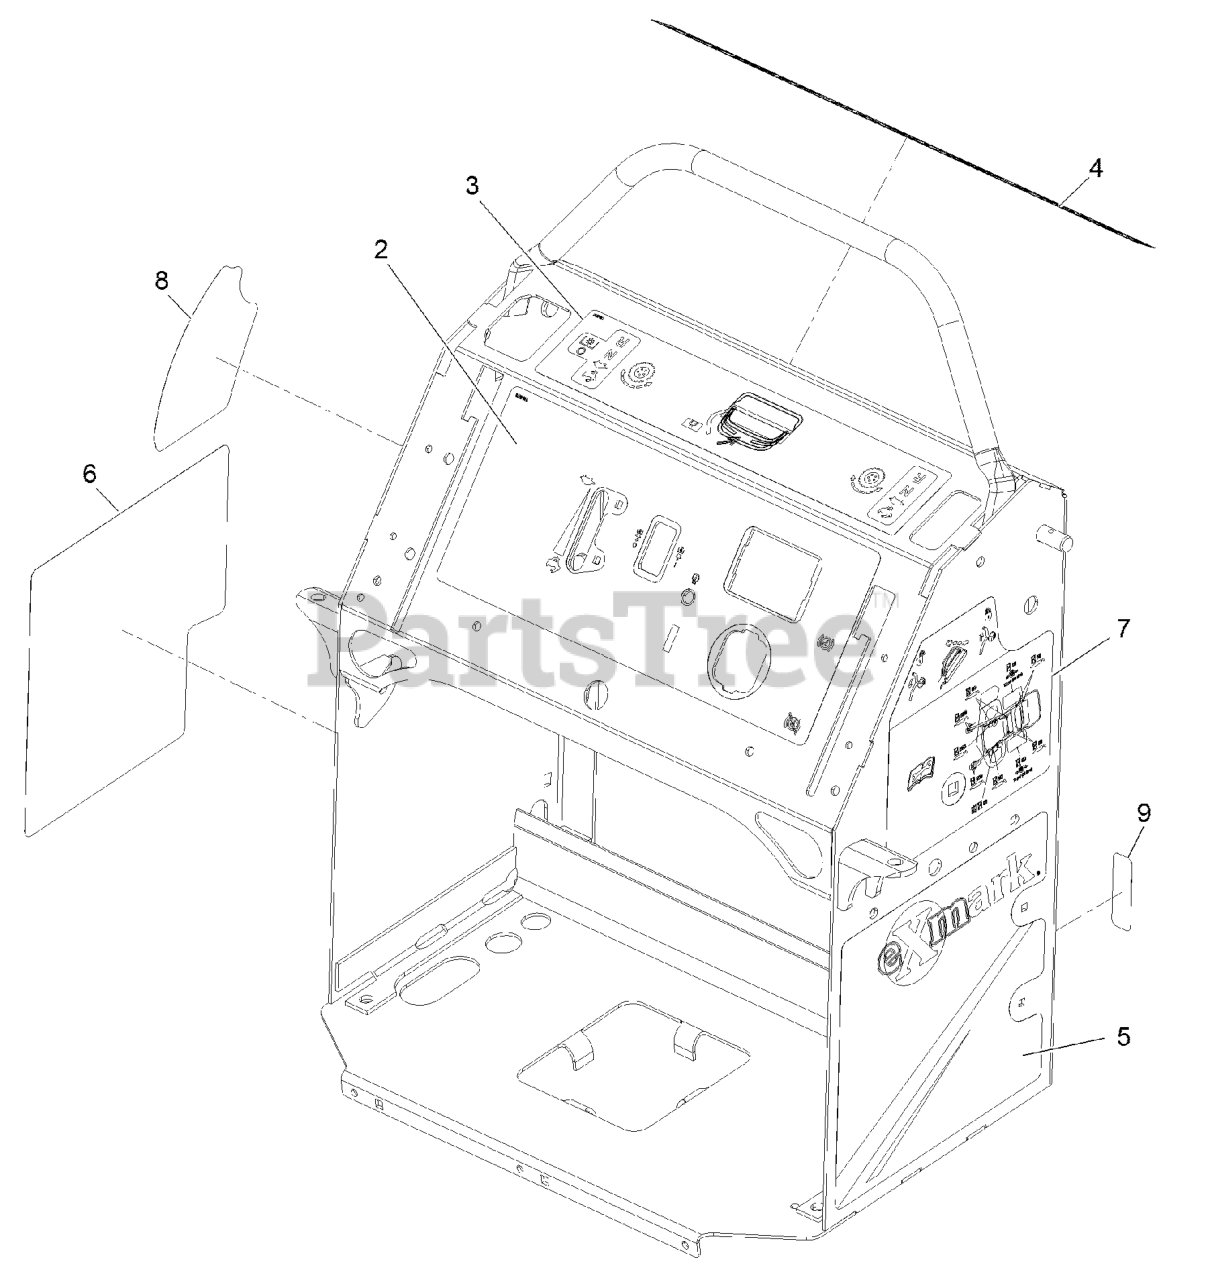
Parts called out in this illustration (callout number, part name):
2	DECAL-CONTROL PANEL EFI
3	DECAL-MOTION CONTROL
4	DECAL-WARNING
5	DECAL-LH PANEL
6	DECAL-RH PANEL
7	DECAL-SERVICE AID
8	DECAL-HEIGHT OF CUT
9	DECAL-FUSE
